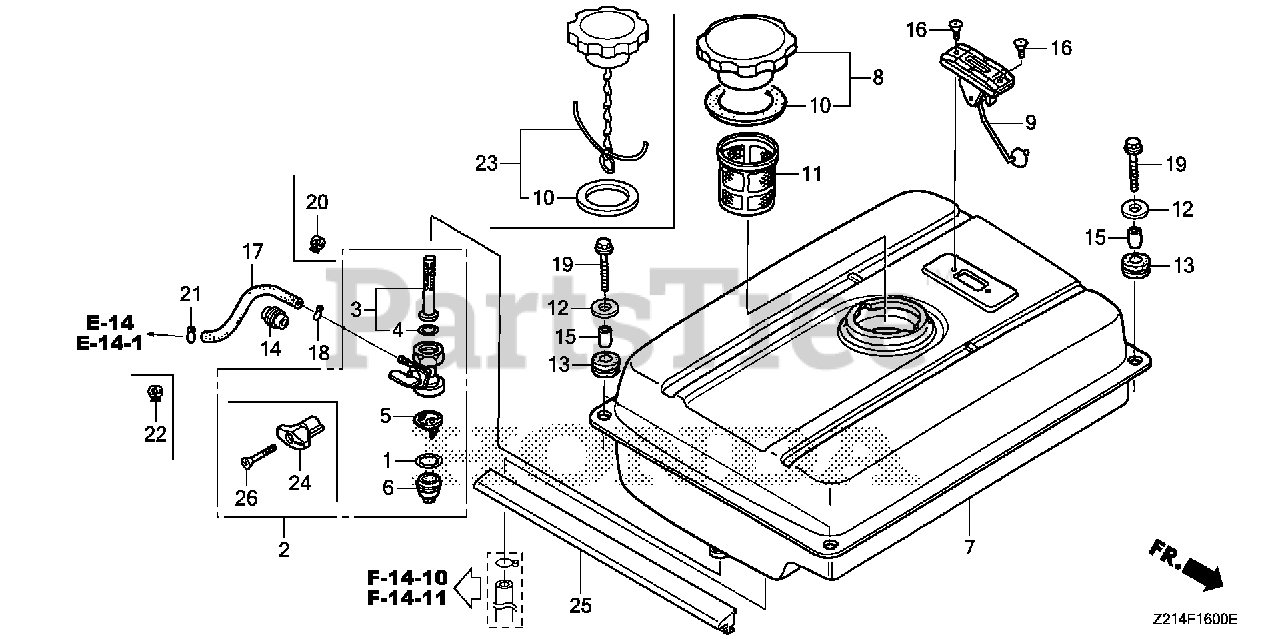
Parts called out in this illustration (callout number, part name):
1	GASKET, FUEL STRAINER CUP
2	PETCOCK ASSY.
3	SCREEN SET, FUEL STRAINER
4	O-RING (9.0X1.3)
5	FILTER, CUP
6	CUP, FUEL STRAINER
7	TANK, FUEL *R280* (POWER RED)
8	CAP, FUEL FILLER
9	METER ASSY., FUEL
10	GASKET, FUEL FILLER CAP
11	FILTER, FUEL
12	WASHER (6MM)
13	RUBBER, TANK CUSHION
14	RUBBER, FUEL (9X15X20)
15	COLLAR, TANK CUSHION
16	SCREW, FLAT (5X10)
17	TUBE, FUEL (4.5X165) (FKM)
17	BULK HOSE, FUEL (4.5X3000) (4.5X165)
18	CLIP, TUBE (B8)
19	BOLT, FLANGE (6X22)
20	CLAMP, TUBE (D8)
21	CLIP, TUBE (B8)
22	CLAMP, TUBE (D8)
